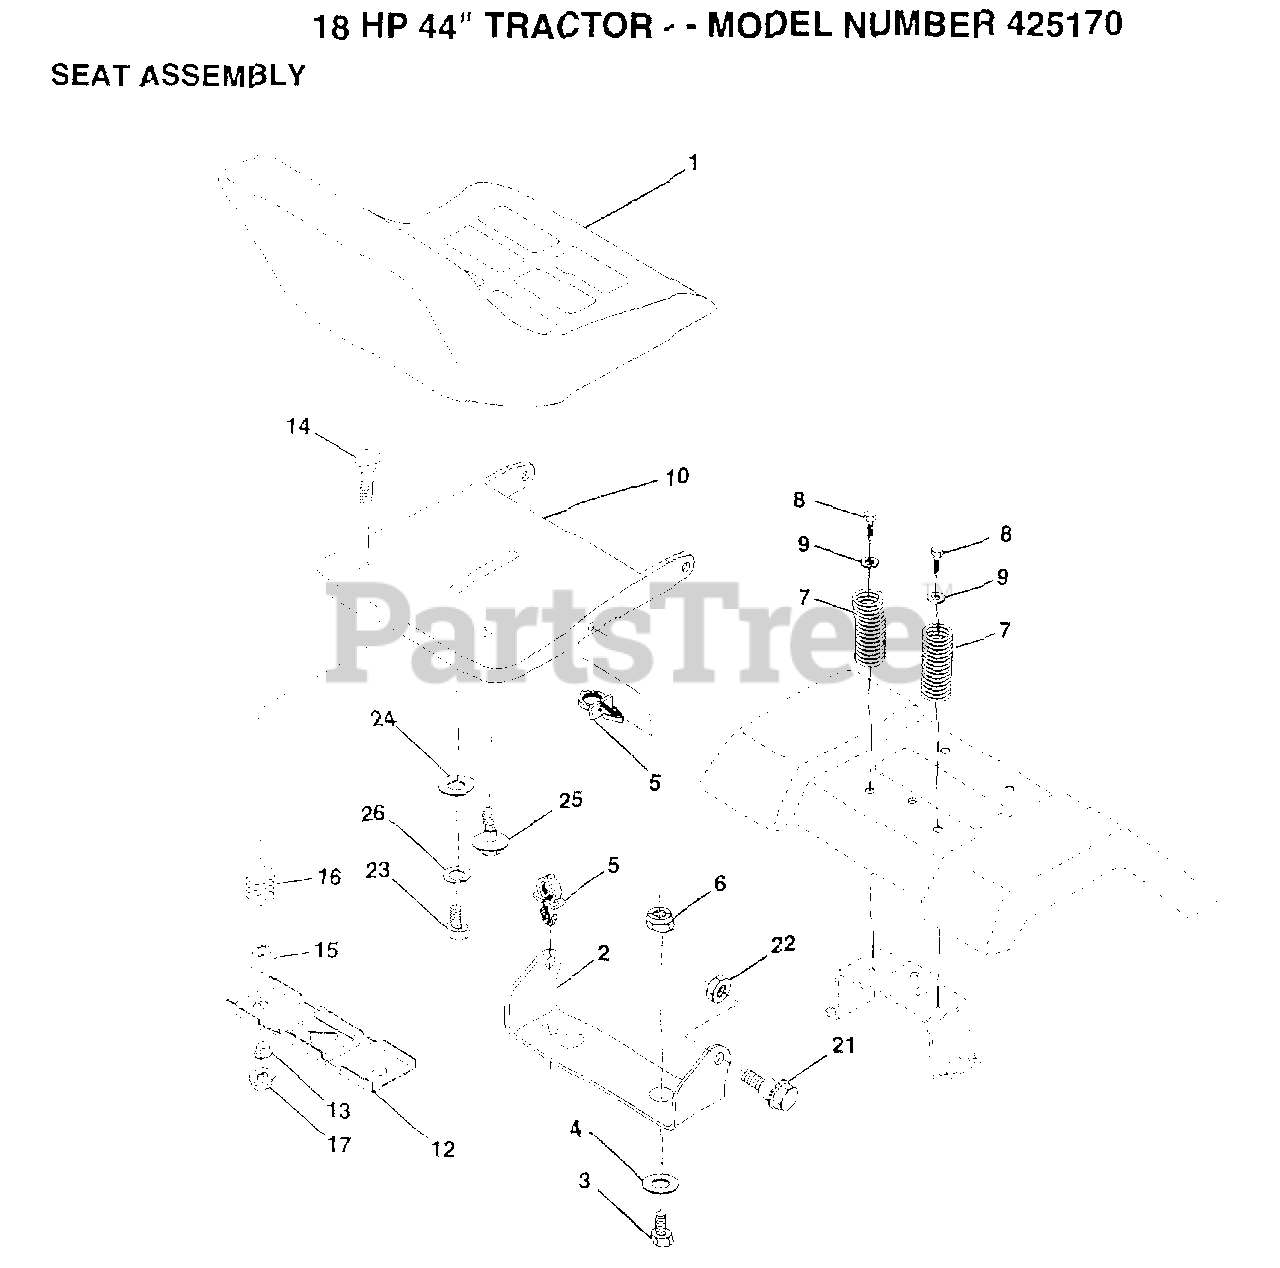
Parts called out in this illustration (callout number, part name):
2	BRACKET PVT SEAT
3	BOLT
4	WASHER PM
5	CLIP PUSH - IN
6	NUT
7	SPRING COMPRESSIO
8	SCREW GTV
9	WASHER
12	BRKT SWITCH
13	BUSHING
15	SPLIT SPACER
16	SPRING
21	BOLT.SHLD.5/16-18
22	NUT
23	BOLT
24	WASHER
25	"BOLT,SHOULDER"
26	LOCKWASHER
